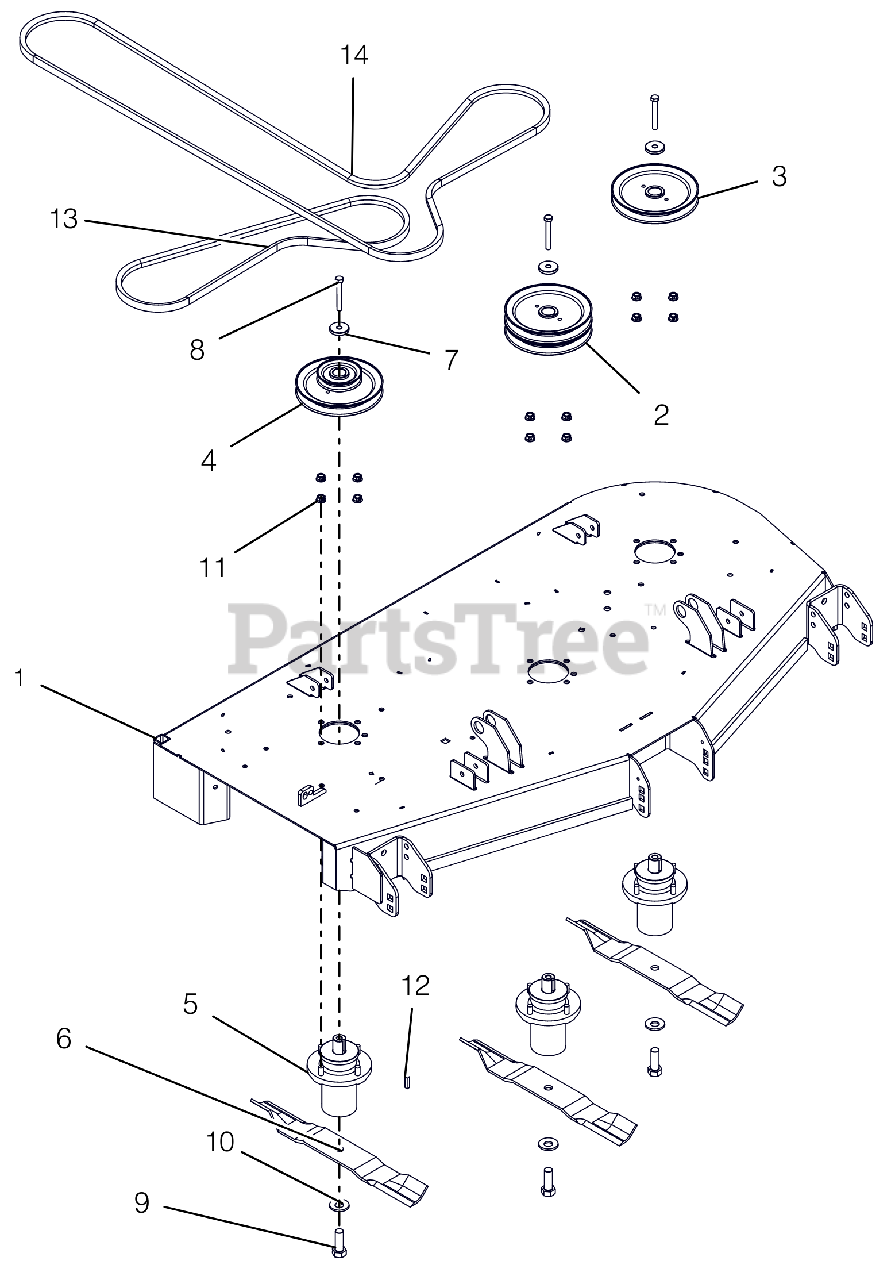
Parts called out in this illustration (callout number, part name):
1	WLDMT, 52" SIDE DISCHARGE DECK
2	PULLEY, DOUBLE-1"ID X 6.75"OD
3	PULLEY, V-1" ID X 6.75" OD
4	PULLEY, DOUBLE-1"IDX3.50"&6.75
5	ASM, MAINT FREE SPINDLE ALUM
6	BLADE, 18"
7	RETAINER, SHEAVE
8	BLT-HEX .38-16X2.75 GR8 YWZC
9	BLT-HEX .62-18X1.75 GR8 YWZC
10	WSHR-BLVL .669X1.535X.138
11	NUT-LK-CTR-FLG .38-16 YWZC
12	KEY, SQ .25X.25X1.00 RC 40-50
13	V-BELT, B-COGGED
14	V-BELT, HB SECTION
